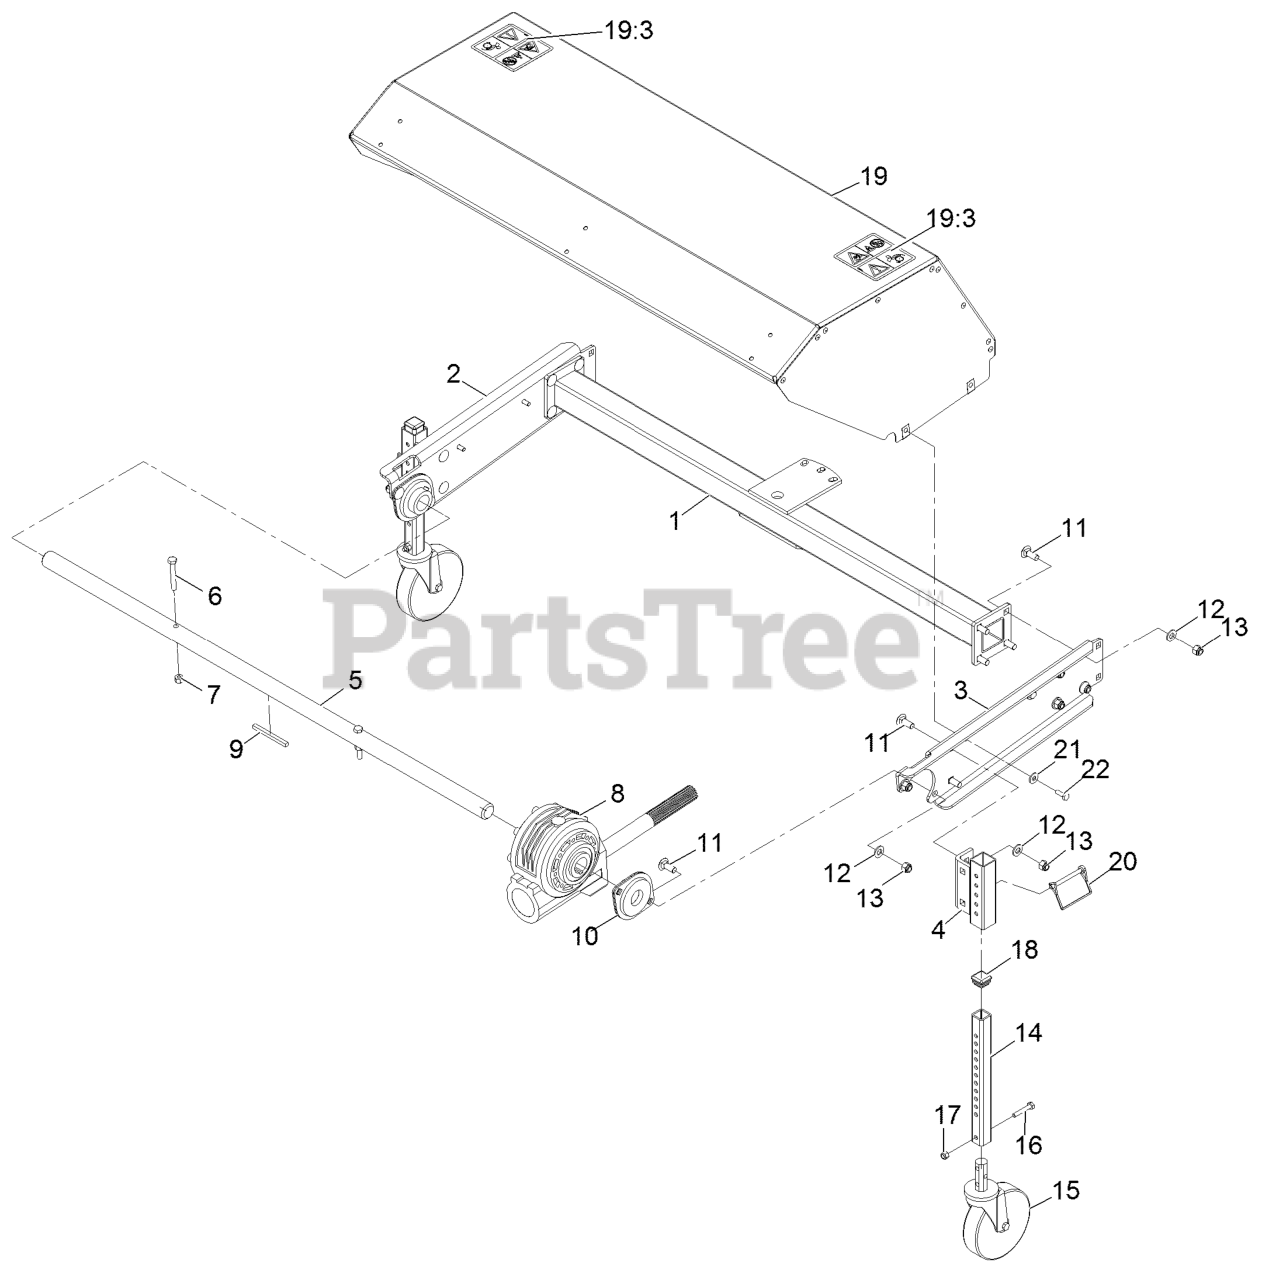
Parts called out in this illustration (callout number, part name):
2	Arm-Right
3	Arm-Left
4	Caster-Bracket
6	Screw-HH 5/16-18 X 2 1/4
7	Nut-Nyloc 5/16-18
8	Gearbox-Worm
9	Key-Straight
10	Bearing-Flange
11	Bolt-Carriage 3/8-16 X 1
12	Washer-3/8 Sae
13	Nut-Nyloc 3/8-16
14	Tube-Square, Height Adjust
15	Caster-Wheel
16	Screw-HH 1/4-20 X 1 1/2
17	Nut-Nyloc 1/4-20
19	Broom Hood ASM
19:3	Decal-Warning
20	Pin-Wire, Lock
21	Washer-1/4 Std
22	Screw-HH 1/4-20 X 3/4
